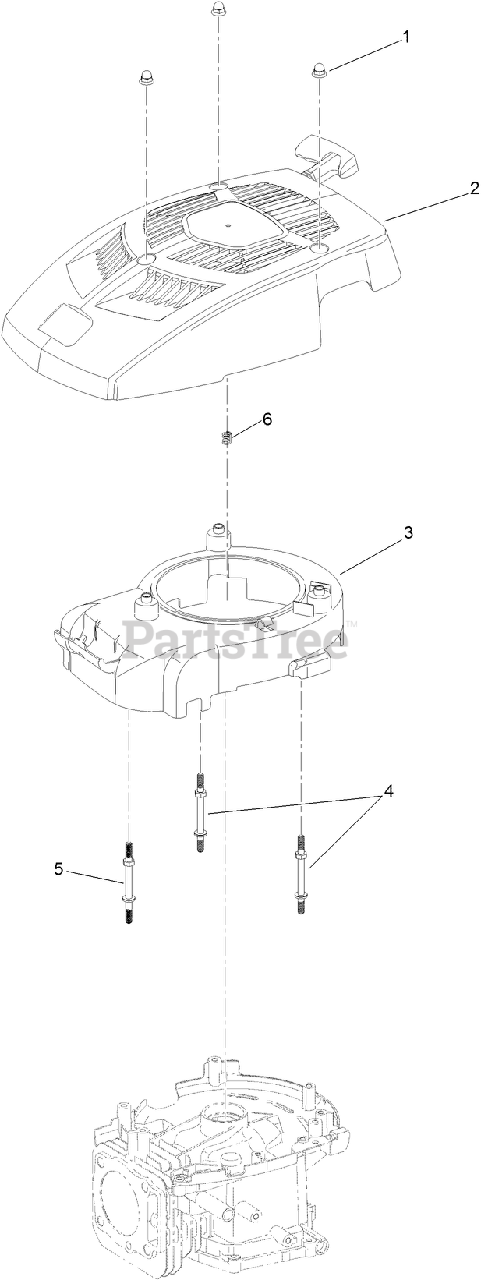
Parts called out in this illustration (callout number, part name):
1	NUT-ACORN
2	RECOIL SHROUD ASM
3	SHROUD-FAN
4	STUD-SHROUD
5	STUD-SHROUD
6	SPRING-COMPRESSION, RECOIL
